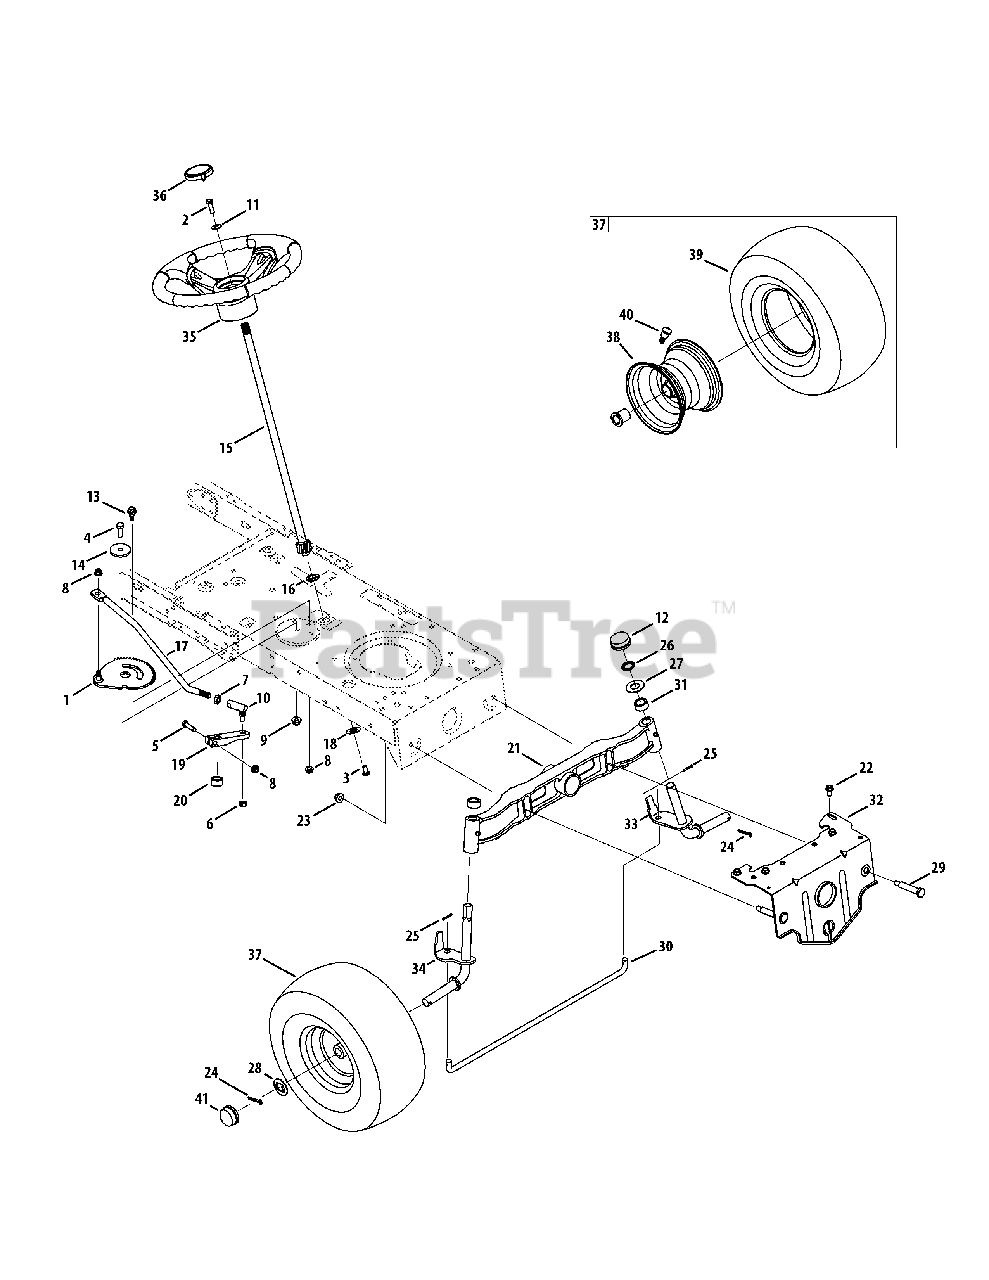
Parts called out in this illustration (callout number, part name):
1	Gear Assembly, Steering
2	Screw, 5/16-18, 1.00, Gr5, Lock
3	Screw, Mach, 5/16-18, 0.750
4	Hex Head Screw, 3/8-16 x 1.00
5	Screw, 5/16-18, 1.75, Gr5
6	Nut, Jam Lock, 3/8-24
7	Nut, Jam, 7/16-20, Gr2
8	Nut, Flange Lock, 5/16-18, Grf
9	Nut, Flange Lock, 3/8-16, Grf
10	Ball Joint, 7/16-20, Lock
11	Washer, Bell, .340 x .872 x .060
12	Hub Cap
13	Shoulder Screw, 5/16-18
14	Shoulder Spacer, .8840 x .190
15	Steering Shaft, 5/8 Spline x 21.86
16	Bearing, Flange, Hex 5/8
17	Drag Link, Steering
18	Cap, 1.25 x .16
19	Steering, Block
20	Spacer, .710 ID x .125 OD x .56
21	Pivot Bar Axle Assembly
22	Screw, 5/16-18, 0.750
23	Nut, Flange Lock, 3/8-16, GrF
24	Pin, Cotter, 5/32, 1.25
25	Pin, Cotter, 1/8 x 0.75
26	Push Cap, 3/4
27	Washer, Flat, .78 x 1.59 x .060
28	Washer, Flat, .781 x 1.59
29	Screw, Shlder, .500 x 2.380, 3/8-16
30	Tie Rod
31	Spacer, .71 x .125 x .56
32	Pivot Bar Bracket
33	Axle Assembly LH
34	Axle Assembly RH
35	Steering Wheel, Standard Grip
36	Cap, Steering Wheel (Crafts. logo)
37	Wheel Assembly
39	Tire, 15 x 6 x 6 Sq. Shoulder
40	Valve Stem
41	Hub Cap
